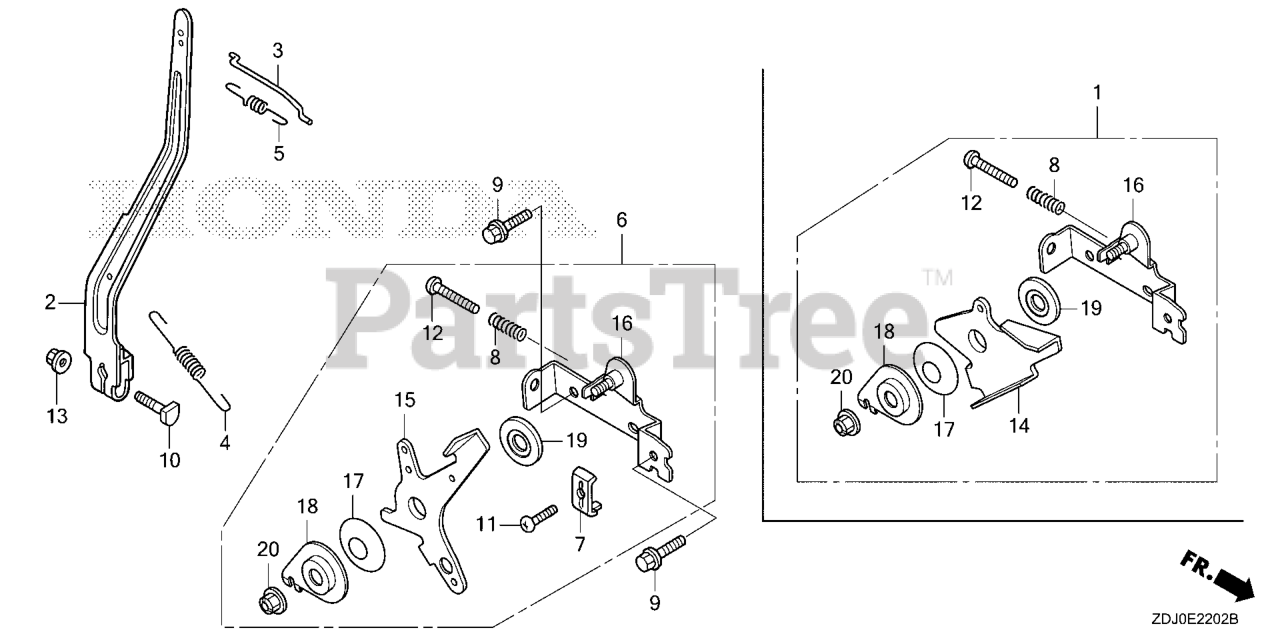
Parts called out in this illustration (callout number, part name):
2	ARM, GOVERNOR
3	ROD, GOVERNOR
4	SPRING, GOVERNOR
5	SPRING, THROTTLE RETURN
6	CONTROL ASSY. (STD)
7	HOLDER, CABLE
8	SPRING, CONTROL ADJUSTING Use from Engine SN 2327377.
9	BOLT, FLANGE (6X14)
10	BOLT, GOVERNOR ARM
11	SCREW, PAN (5X16)
12	SCREW, PAN (5X25)
13	NUT, FLANGE (6MM)
15	CONTROL ASSY. (STD)
16	BASE, CONTROL (STD)
17	SPRING, LEVER
18	WASHER, CONTROL LEVER
19	SPACER, CONTROL LEVER
20	NUT, SELF-LOCK (6MM)
